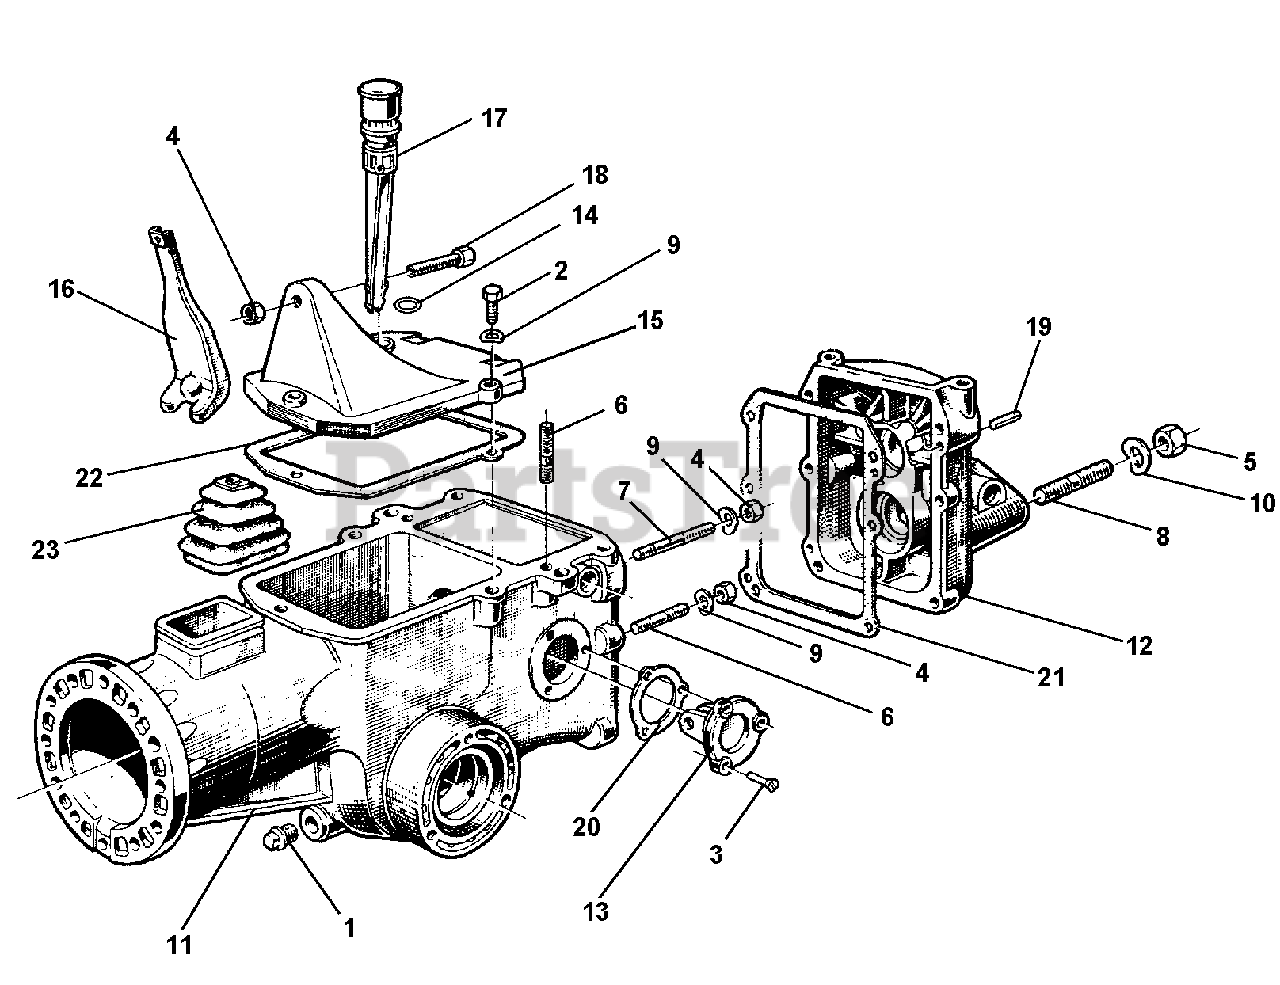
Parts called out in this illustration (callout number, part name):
1	PLUG 1/4 GAS
2	SCREW TE M8 X 25
3	SCREW TSV M6 X 16 UNI 260-5S
5	NUT M12 X 1.25 UNI 5587 6S
6	STUD M8 X 38 X 14 X 20
7	STUD M8 X 58 X 16 X 16
8	STUD 56XM12X1.25X26XM12X228G
9	WASHER, LOCK 8.4
10	WASHER, LOCK 13
11	HOUSING BODY
12	HOUSING COVER
13	FLANGE, REVERSE SPEED
14	RUBBER RING
15	GEARBOX COVER
16	CLUTCH LEVER
17	CAP, WITH MEASURING ROD
18	SCREW, ADJUSTING M8
19	PARALLEL PIN D 6 X 20
21	GASKET, COVER
22	GASKET, COVER
